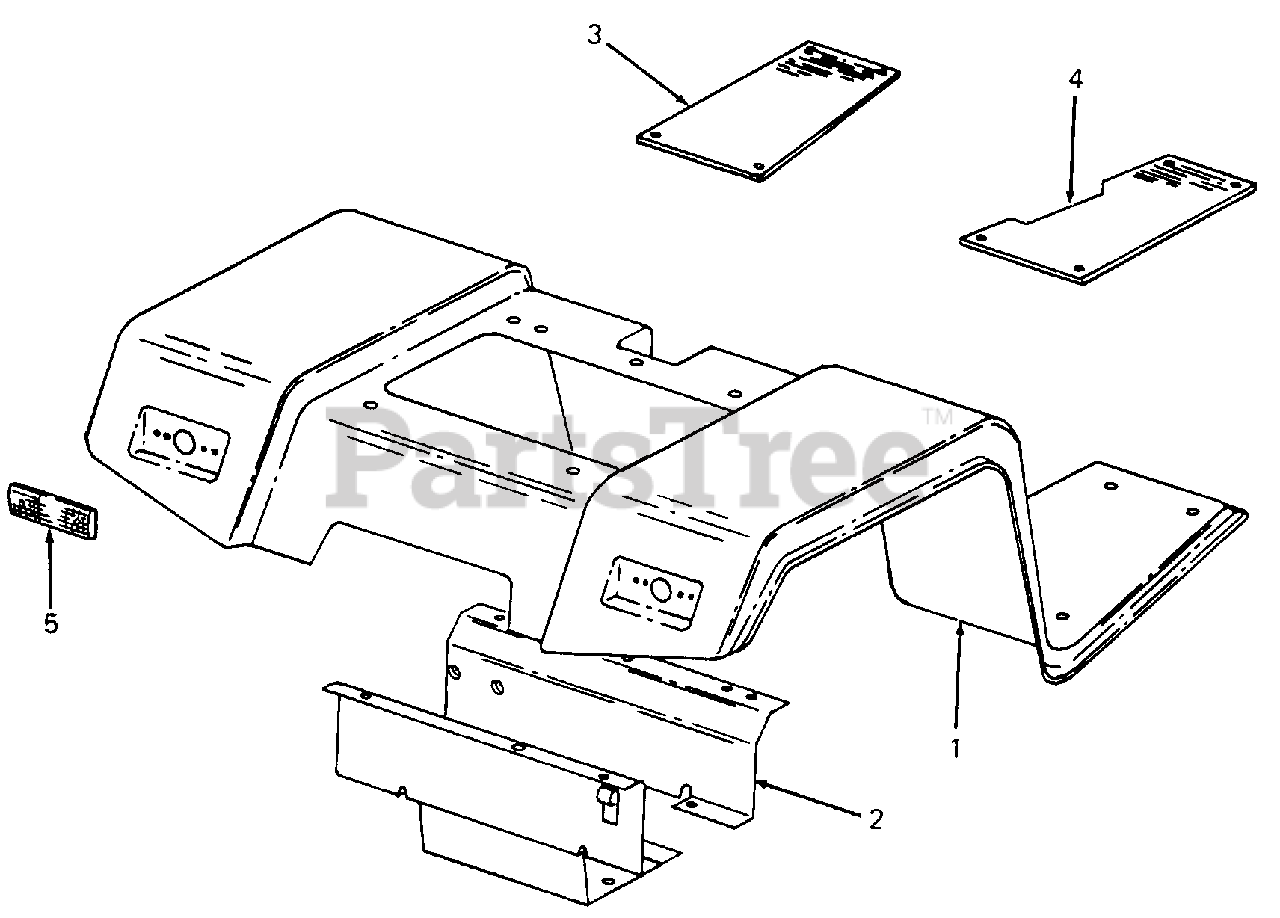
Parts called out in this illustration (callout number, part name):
2	Support, Fender
3	Pad, LH - Foot
4	Pad, RH - Foot
5	Reflector
